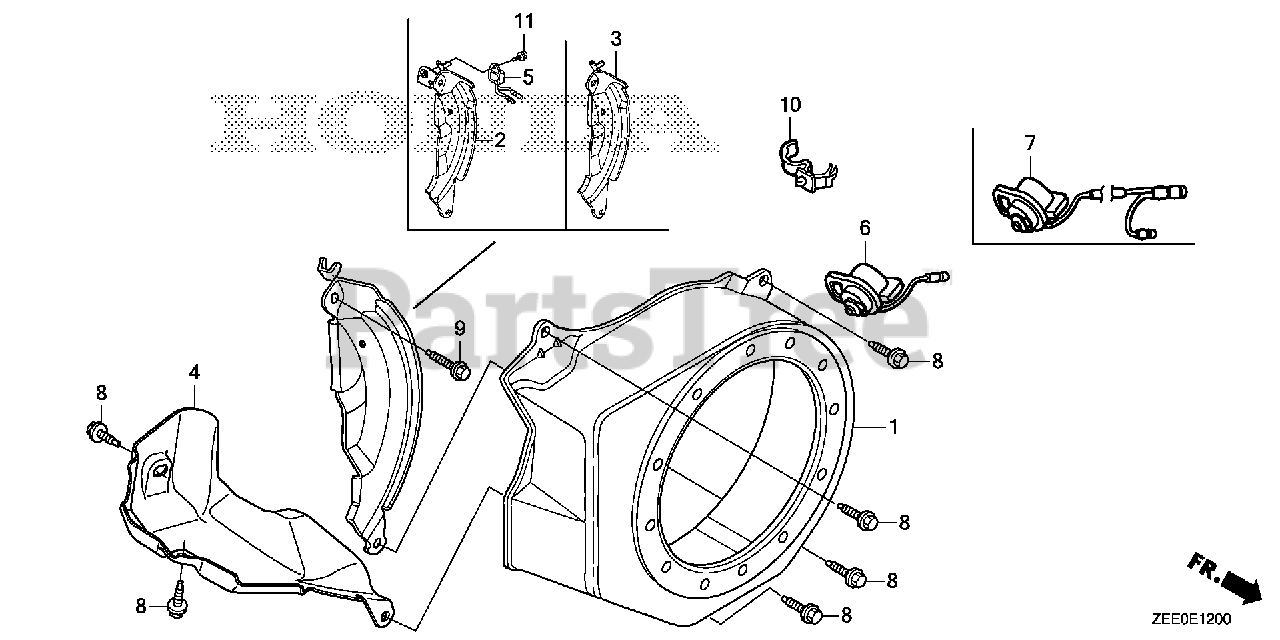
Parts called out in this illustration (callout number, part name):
1	COVER, FAN *R280* (POWER RED)
3	PLATE, SIDE (STD)
6	SWITCH ASSY., ENGINE STOP
6	SWITCH ASSY., ENGINE STOP (TOYO DENSO)
6	SWITCH ASSY., ENGINE STOP (MINDA)
8	BOLT, FLANGE (6X12) (CT200)
9	BOLT, FLANGE (6X20) (CT200)
